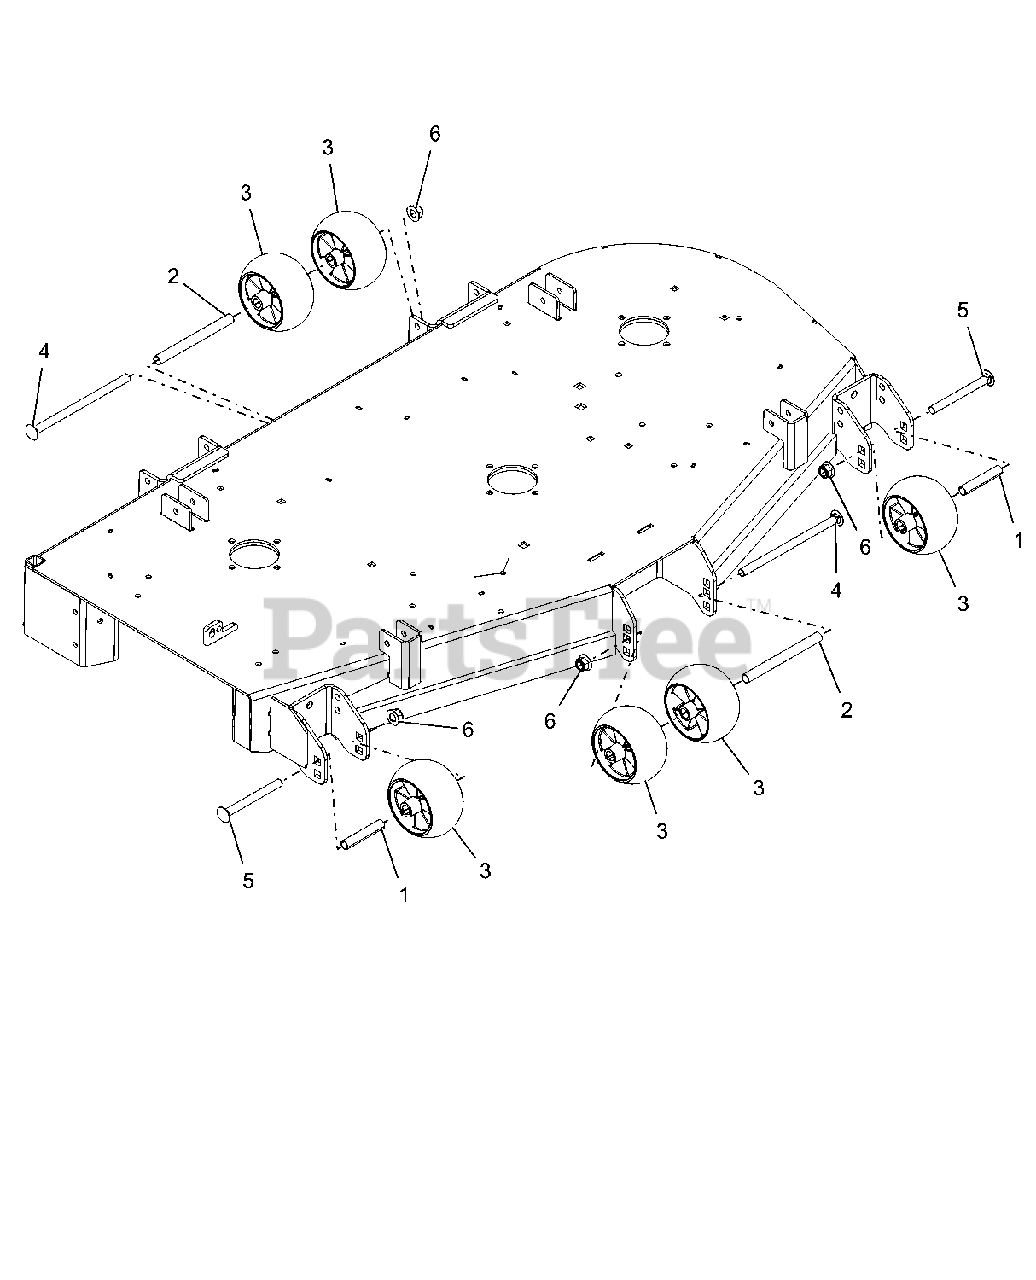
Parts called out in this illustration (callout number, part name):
1	SPACER, .510X.625X3.35
2	SPACER, .510 X .625 X 6.50
3	ANTI-SCALP WHEEL - 5X3 CTR
4	BLT-RDHDSQNK .50-13X8.50 Y
5	BLT-RDHDSQNK .50-13X5.00 G5 YWZC
6	NUT-LK-NYL-FLG .50-13 YWZC
